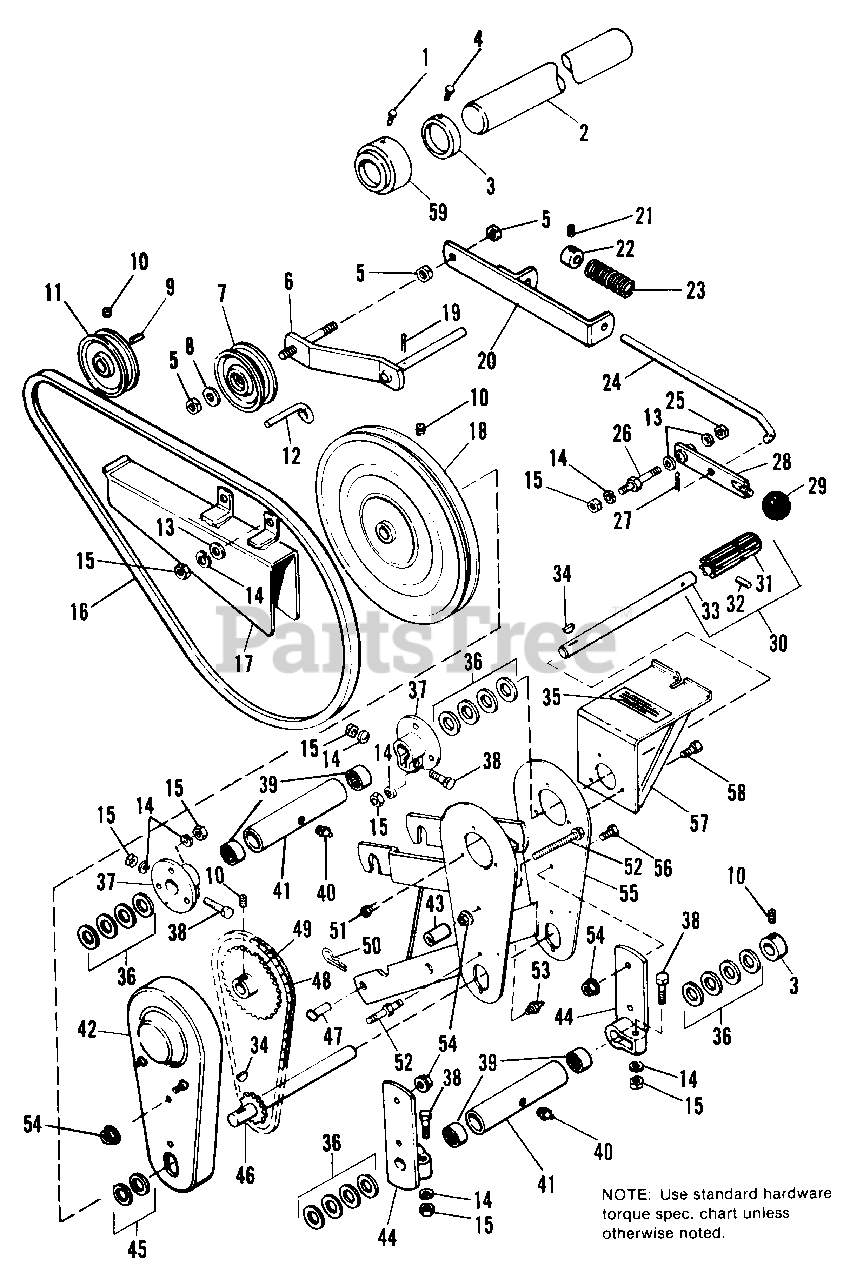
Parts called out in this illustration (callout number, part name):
1	SETSCREW, Sq. Hd., 5/16-18 x 5/8
2	SHAFT, Lift
3	COLLAR, Set
4	SETSCREW, Sq. Hd., 5/16-18 x 1/2
5	LOCKNUT, Hex, 3/8-16
6	PIVOT ASSY.
7	PULLEY, Idler
8	WASHER, Plain, 3/8
9	KEY, Sq., 3/16 x 1
10	SETSCREW, Hex, Socket Hd., 5/16-18 x 5/16
13	WASHER, Plain, 5/16
14	LOCKWASHER, 5/16
15	NUT, Hex, Full, 5/16-18
16	BELT, Drive
17	GUARD ASSY., Belt & Pulley
18	PULLEY, (Incl. Ref. No. 10)
19	PIN, Cotter, 1/8 x 1
20	GUIDE ASSY., Clutch
21	SETSCREW, Sq. Hd., 1/4-20 x 3/8
22	COLLAR, Set
24	ROD, Clutch
25	LOCKNUT, Hex, 5/16-18
27	COTTER PIN, 3/32 x 3/4
28	HANDLE ASSY.
30	SHAFT ASSY. (Incl. Ref. Nos. 31 & 33)
32	PIN, Dowel
34	KEY, Woodruff, #9, 3/16 x 3/4
35	DECAL, Warning
37	FLANGE ASSY.
38	CAPSCREW, Hex Hd., 5/16-18 x 1-1/2
39	BEARING, Needle
40	FITTING, Grease, 1/4-28
41	HOUSING, Needle
42	GUARD ASSY.
43	SPACER, Latch
44	SUPPORT ASSY., Clamp
46	SHAFT ASSY.
50	CLIP, Spring (Serviced 5 in a pack)
51	CAPSCREW, Hex Hd., 5/16-18 x 5/8
52	SCREW, Flange, Whiz., 3/8-16 x 2-1/4 (Later models)
52	STUD (Earlier models)
53	FITTING, Grease, Drive, 1/4
54	NUT, Hex, Whizlock 3/8-16
55	FRAME ASSY.
56	CAPSCREW, Hex Hd., 3/8-16 x 3/4
57	GUARD ASSY., PTO
58	CAPSCREW, Hex Hd., 5/16-18 x 3/4
59	COLLAR, Set
